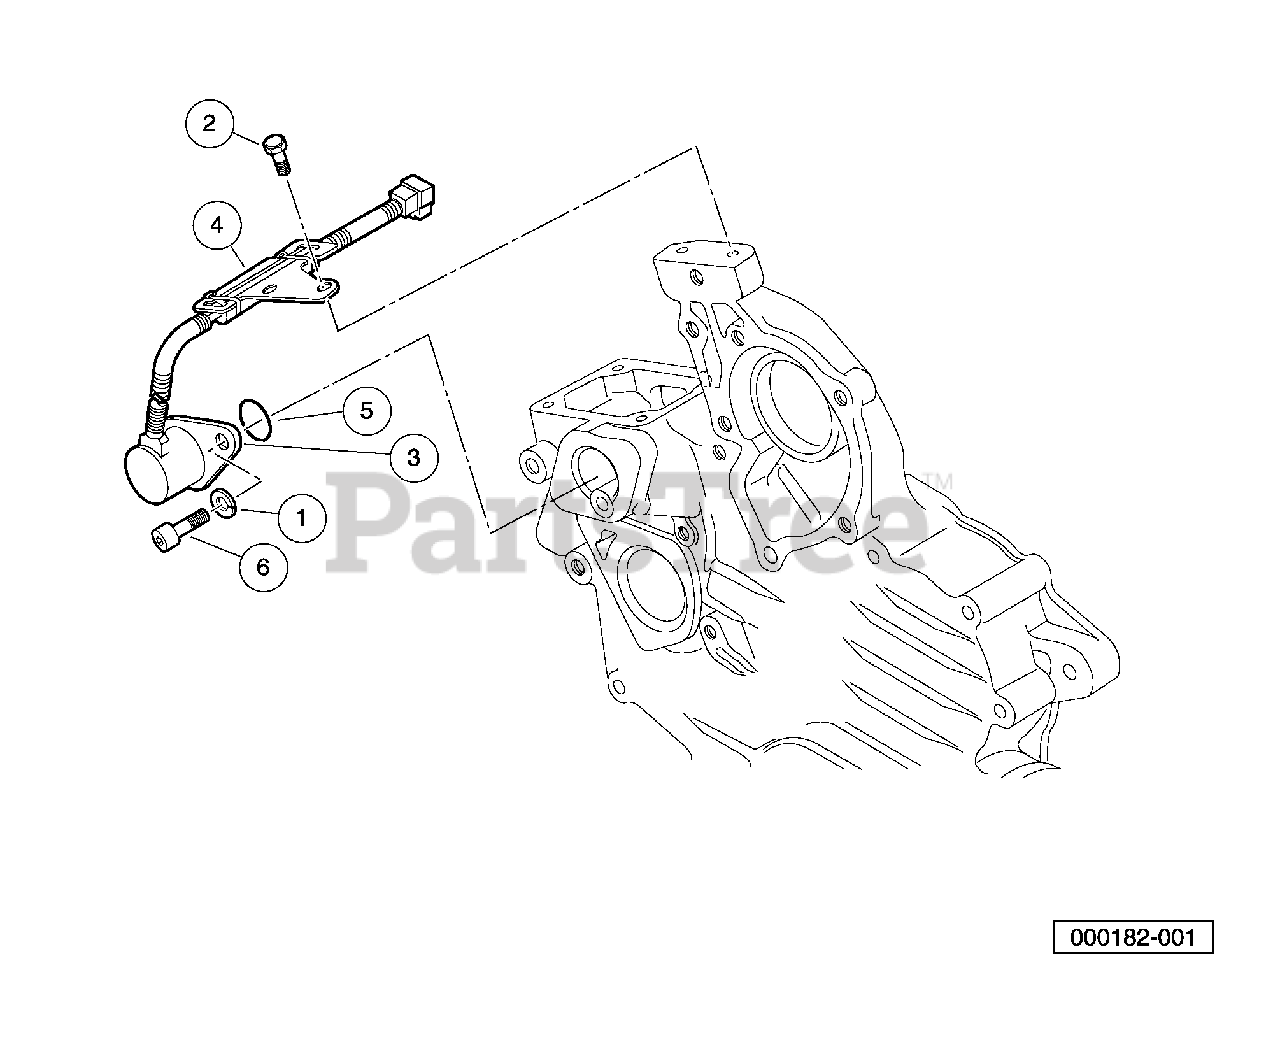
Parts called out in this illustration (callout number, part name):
1	Washer, Spring, M6, D722
2	Bolt, Solenoid, Stop, D722
3	Solenoid, Stop
4	Stay, Stop Solenoid
5	O-Ring, Stop Solenoid
6	Bolt, Stop Solenoid
